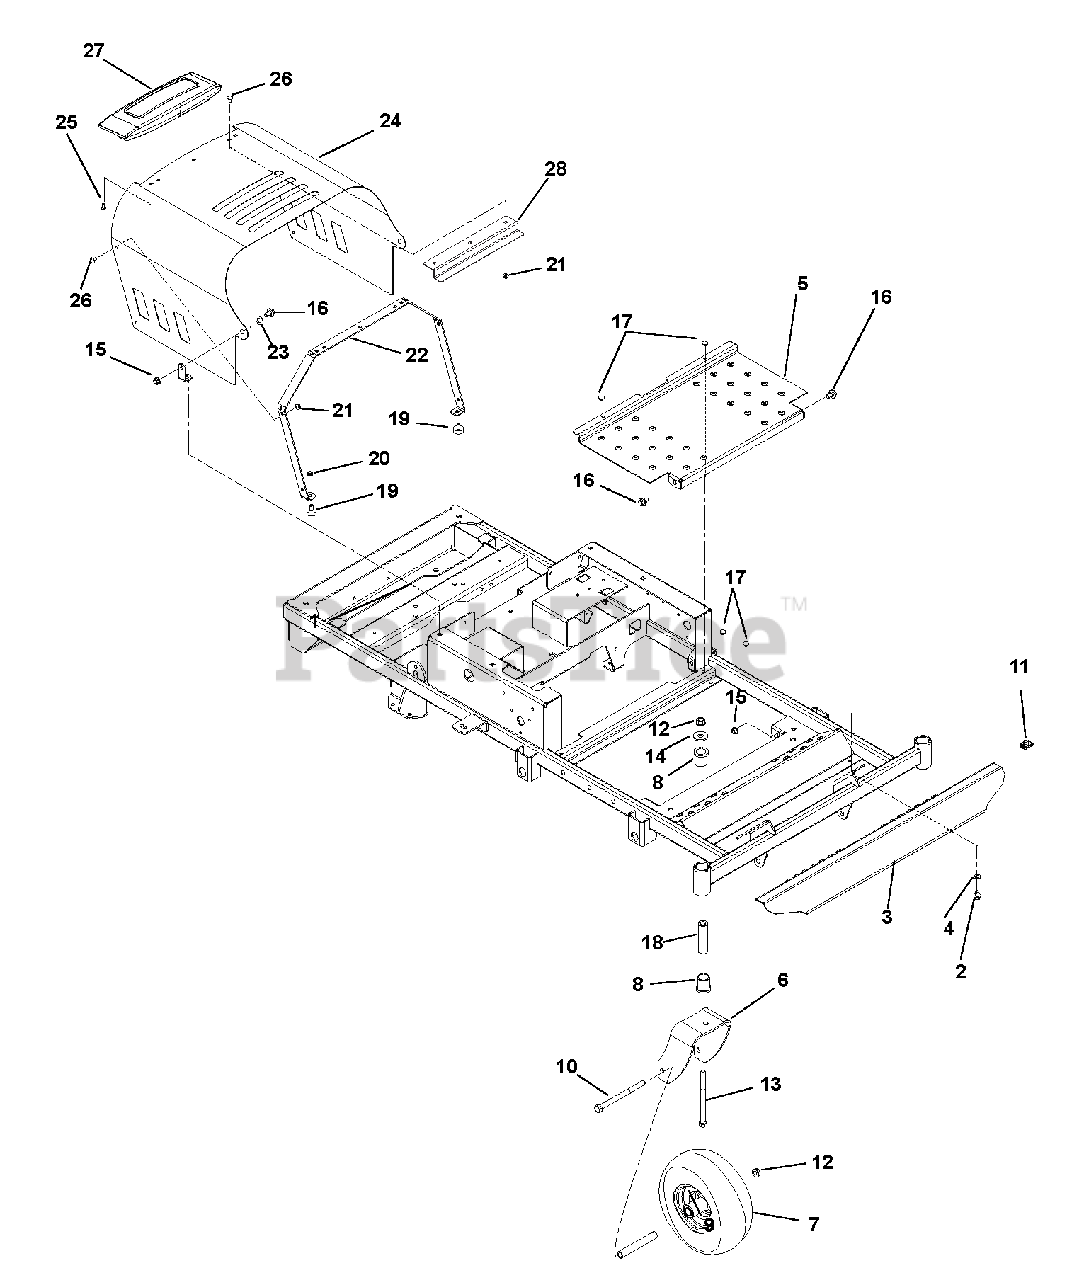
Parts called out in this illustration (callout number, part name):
1	WLDMT, FRAME ZT/ZOOMXL (2013)
2	@BLT-HEX .38-16X1.00 GR5 YWZC
3	WMT, FOOTREST
4	@WSHR-LK .38X.094 REG YWZC
5	DECK ACCESS PANEL
6	WMT, CASTER FORK
7	TIRE/WHEEL ASSY, 11X4-5
8	BSHG-FLG 1.00X1.25X1.50X1.50
9	SPACER, ROLLED WHEEL
10	@BLT-HEX .50-13X6.50 GR5 YWZC
11	NUT-RTNR .375-16X.37
12	@NUT-LK-TOP-FLG .50-13 YWZC
13	@BLT-HEX .50-13X5.00 GR5 YWZC
14	WSHR-FL-STL.511X1.441X.125 YWZ
15	@NUT-LK-TOP-FLG .38-16 YWZC
16	BOLT-SHLDR .375-16X.150
17	BUMPER GROMMET
18	SPACER, CASTER FORK
19	BUMPER, RUBBER
20	@NUT-LK-TOP-FLG .31-18 YWZC
21	@NUT-LK-TOP-FLG .25-20 YWZC
22	HOOD STRAP
23	WSHR-FL-NYL .518X1.000X.080
24	HOOD, XL
25	SCR-.25X.62 PN HD BOSSSCREW YZ
26	@BLT-RDHDSQNK .25-20X.50 G5YZ
27	TRIM-ZOOM XL HOOD ARIENS
28	BRKT, ENGINE GUARD
